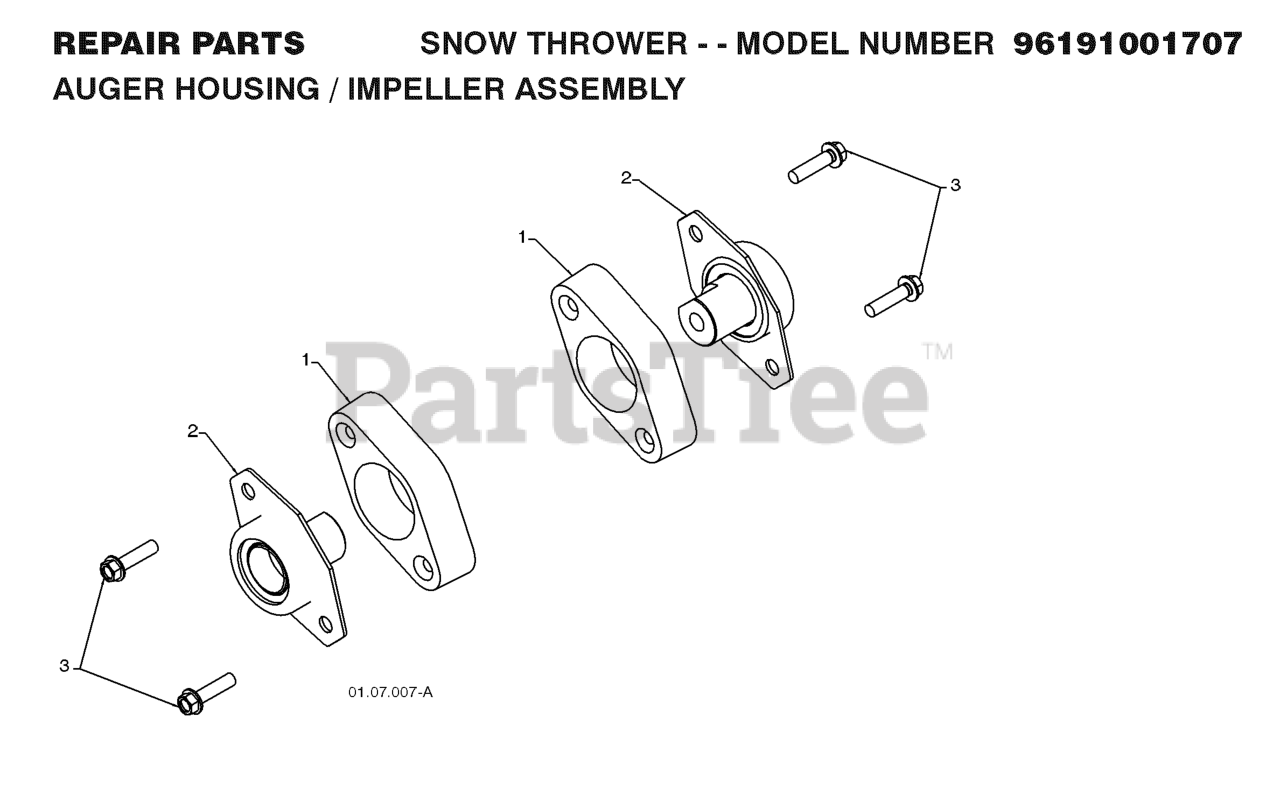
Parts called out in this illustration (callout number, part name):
1	BEARING RETAINER, PLASTIC
2	BEARING.BALL.AUGER
3	SCREW, HEX HD 5/16X1
